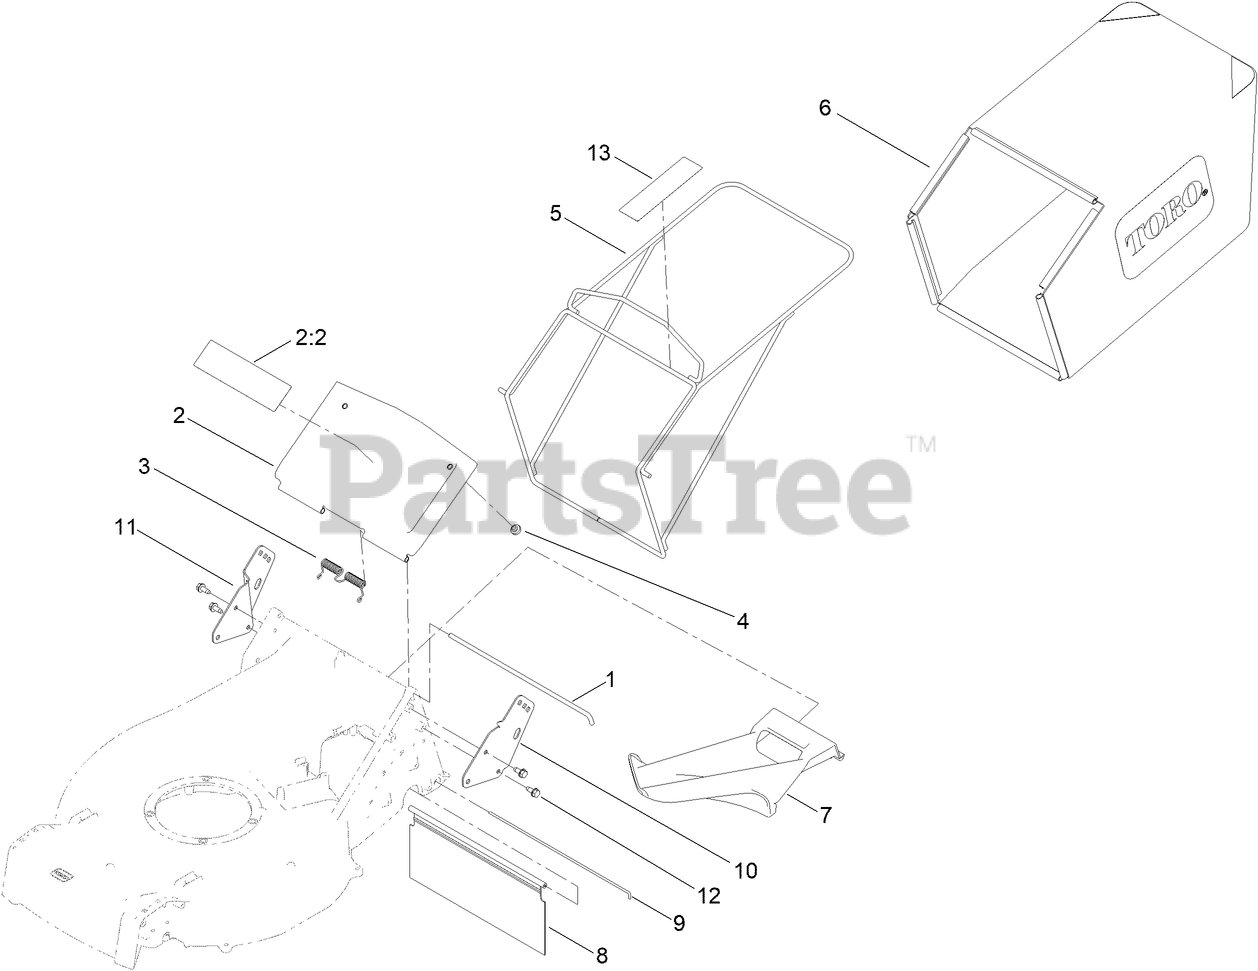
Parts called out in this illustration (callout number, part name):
1	ROD-DOOR, BAG
2	BAG DOOR ASM
2:2	DECAL-WARNING
3	SPRING-TORSION
4	BUMPER
5	FRAME-BAG
6	BAG-GRASS
7	PLUG-MULCH
8	SHIELD-TRAILING
9	ROD-SHIELD, TRAILING
10	BRACKET-MOUNT, HANDLE (LH)
11	BRACKET-MOUNT, HANDLE (RH)
12	SCREW-HWHTF
13	DECAL-WARNING (BAG)
